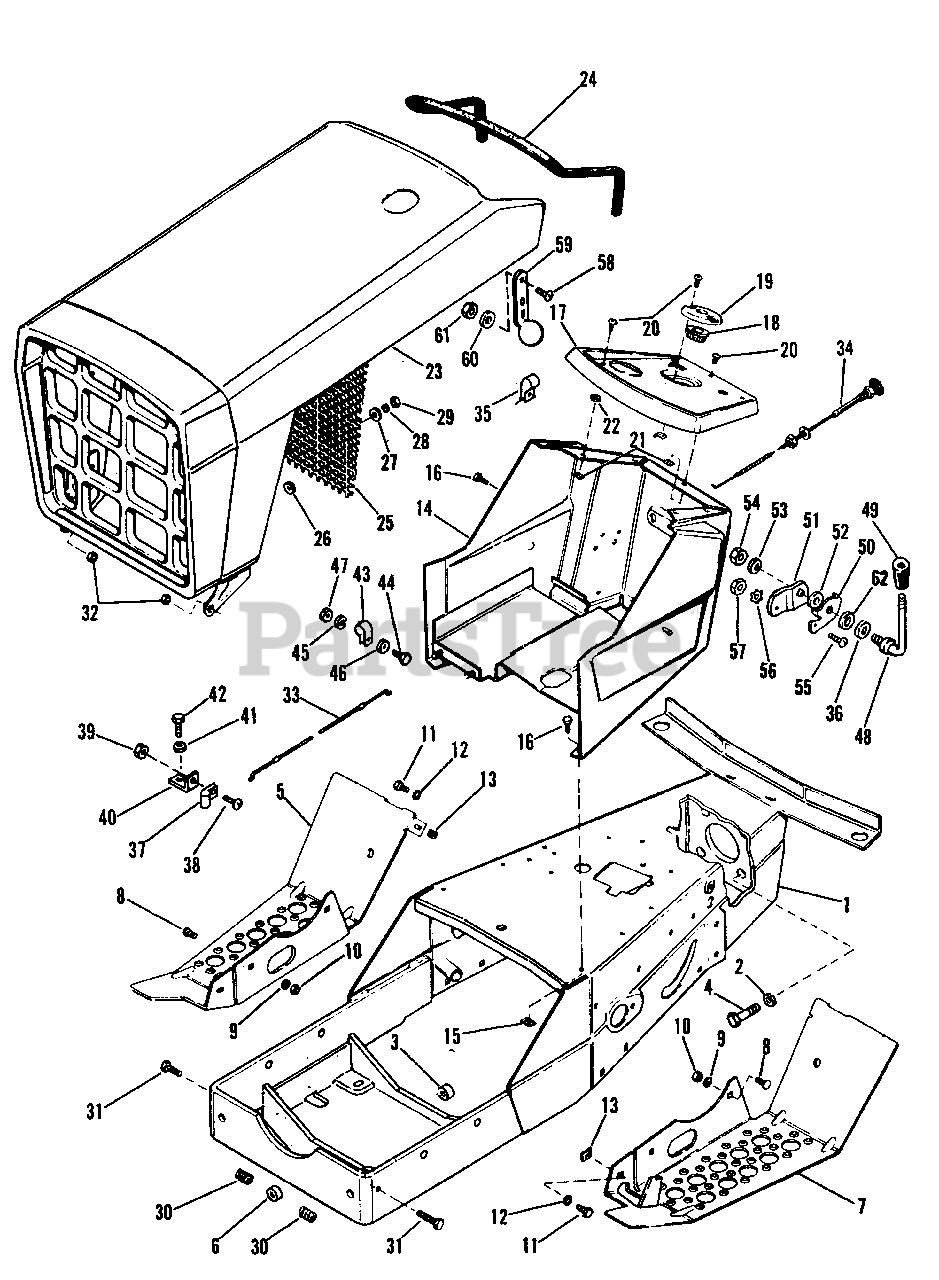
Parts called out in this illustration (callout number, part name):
1	FRAME ASSEMBLY
2	LOCKWASHER, 7/16"
4	CAPSCREW, Hex, 7/16"-14 x 1-1/2" lg.
5	FOOT REST, R.H.
7	FOOT REST, L.H.
8	BOLT, Carriage, 5/16"-18 x 3/4" lg.
9	LOCKWASHER, 5/16"
10	NUT, Hex, Full, 5/16"-18
11	CAPSCREW, Hex, 5/16"-18 x 3/4" lg.
12	LOCKWASHER, 5/16"
13	NUT, Tinnerman
14	DASH ASSEMBLY
15	NUT, Tinnerman
16	SCREW, Hex, #14 x 3/4" lg.
17	PANEL, Instrument
18	BUSHING, Steering
19	PLATE, Steering Adj.
20	SCREW, Rd., Phillips 1/4"-20 x 1/2" lg.
21	NUT, Tinnerman
22	WASHER, Plain 3/16"
23	GRILL & HOOD ASSEMBLY
24	MOLDING, Hood
25	SCREEN, Grille
28	LOCKWASHER, Shakeproof #10
29	NUT, Hex, Full, #10-24
31	CAPSCREW, Hex, 3/8"-16 x 1-1/2" lg.
32	NUT, Hex, Full, Lock, 3/8"-16
33	CONTROL, Throttle
34	CONTROL, Choke
35	CLIP, Bowden, Wire
37	CLIP, Bowden, Wire
38	SCREW, Rd. Hd. #10-32 x 3/8" lg.
39	NUT, Hex, Full, #10-32
40	BRACKET, Throttle
41	LOCKWASHER, 1/4"
42	SCREW, Self-Tapping, 1/4"-20 x 5/8" lg.
44	CAPSCREW, Hex, 1/4"-20 x 5/8" lg.
45	LOCKWASHER, 1/4"
46	WASHER, Plain, 1/4"
47	NUT, Hex, Full, 1/4"-20
48	HANDLE, Clutch
49	KNOB
50	STOP, Throttle
51	ARM, Throttle
53	LOCKWASHER, Shakeproof, 3/8"
54	NUT, Hex, Full, Lock, 3/8"-16
55	SCREW, Mach, Rd., Hd. #10-32 x 1/2"
56	LOCKWASHER, Shake proof #10[
57	NUT, Hex, Full, #10-32
58	SCREW, Truss Hd, Phillips #10-32 x 1/4" lg.
59	STRAP, Hood
61	NUT, Center Lock, #10-32
